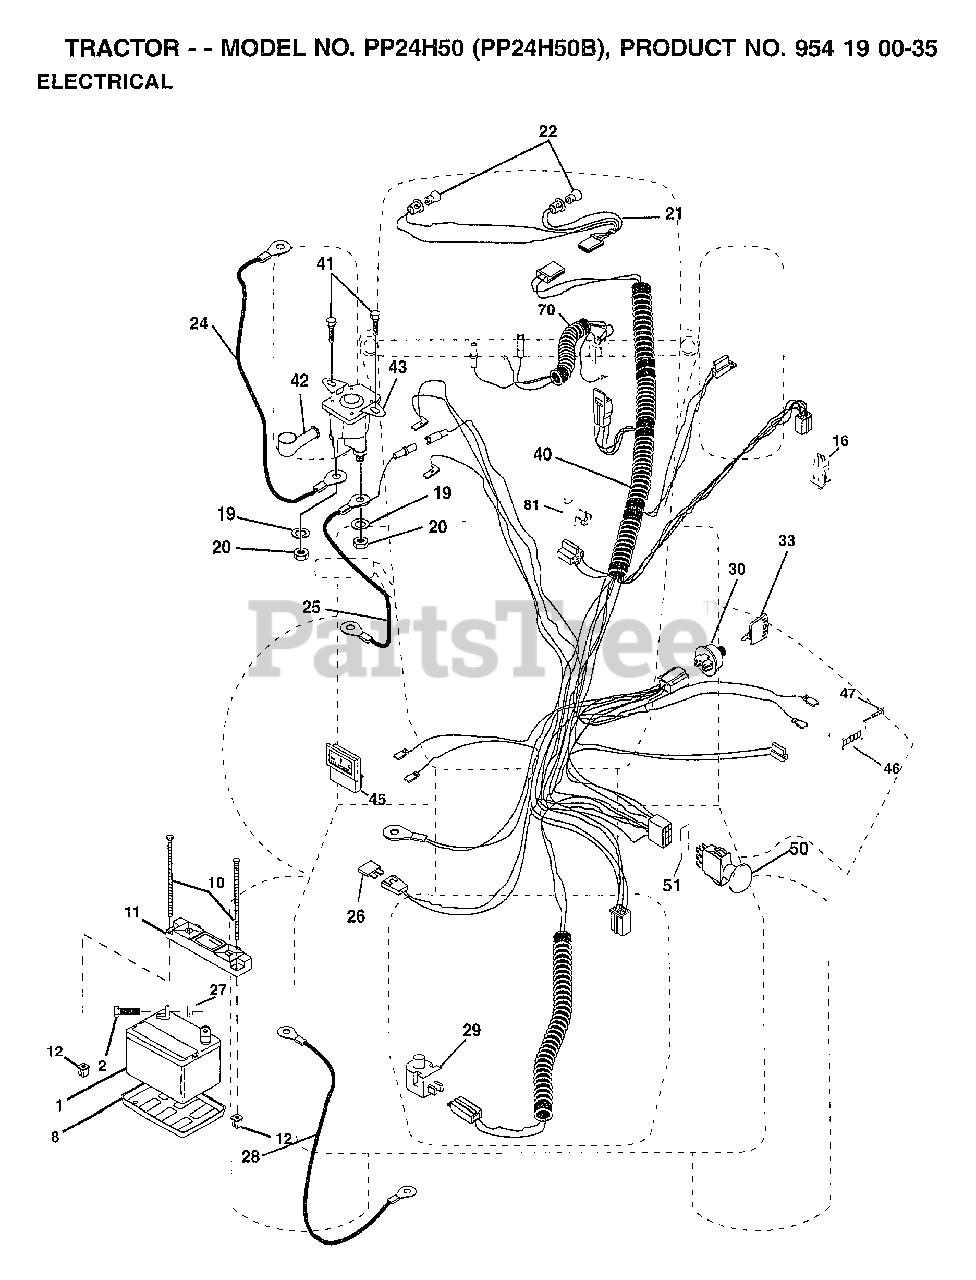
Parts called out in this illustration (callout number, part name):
2	BOLT LT
8	"TRAY T, BATTERY"
11	HOLDDOWN BATTERY
16	SWITCH INTERLOCK
20	NUT
21	HARNESS.ASM.LIGHT.W/4152J
22	HEADLAMP BULB
24	CABLE.6GA.12.5.
25	CABLE-BATTERY T
26	FUSE HYT
27	NUT
28	CABLE T
29	SWITCH.PLUNGER
30	SWITCH.IGN.
33	KEY MLD GEN DELTA
40	HARNESS.IGN.
41	SCREW
45	AMMETER
46	HOUR METER T
47	SCREW
50	PTO SWITCH.BLK
51	RING RETAIN PTO
70	HARNESS.ENGINE
81	RELAY ASSY T
